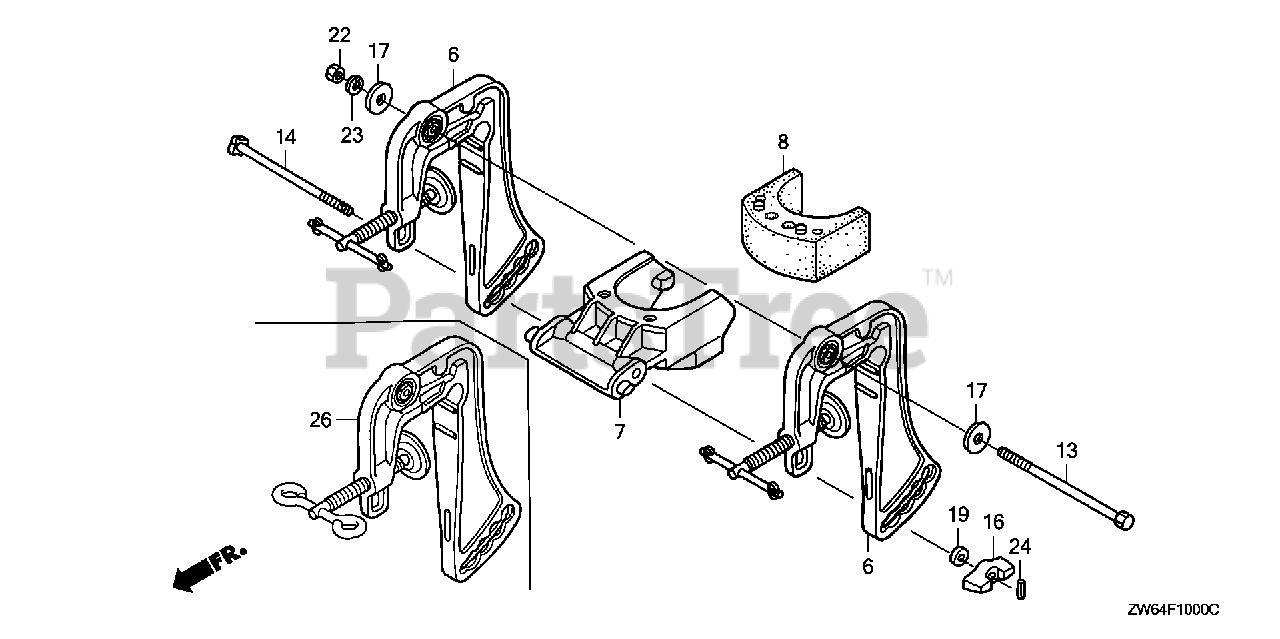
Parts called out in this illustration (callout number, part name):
6	BRACKET, STERN *NH246* (LOOSY GRAY)
7	RECEIVER, THRUST
8	RUBBER, THRUST
13	BOLT, HEX. (8X110)
14	BOLT, DIAMOND (6X110)
16	WINGNUT
17	WASHER, PLAIN (8MM)
19	WASHER, PLAIN (6MM)
22	NUT, HEX. (8MM)
24	PIN, SPRING (2.5X8)
